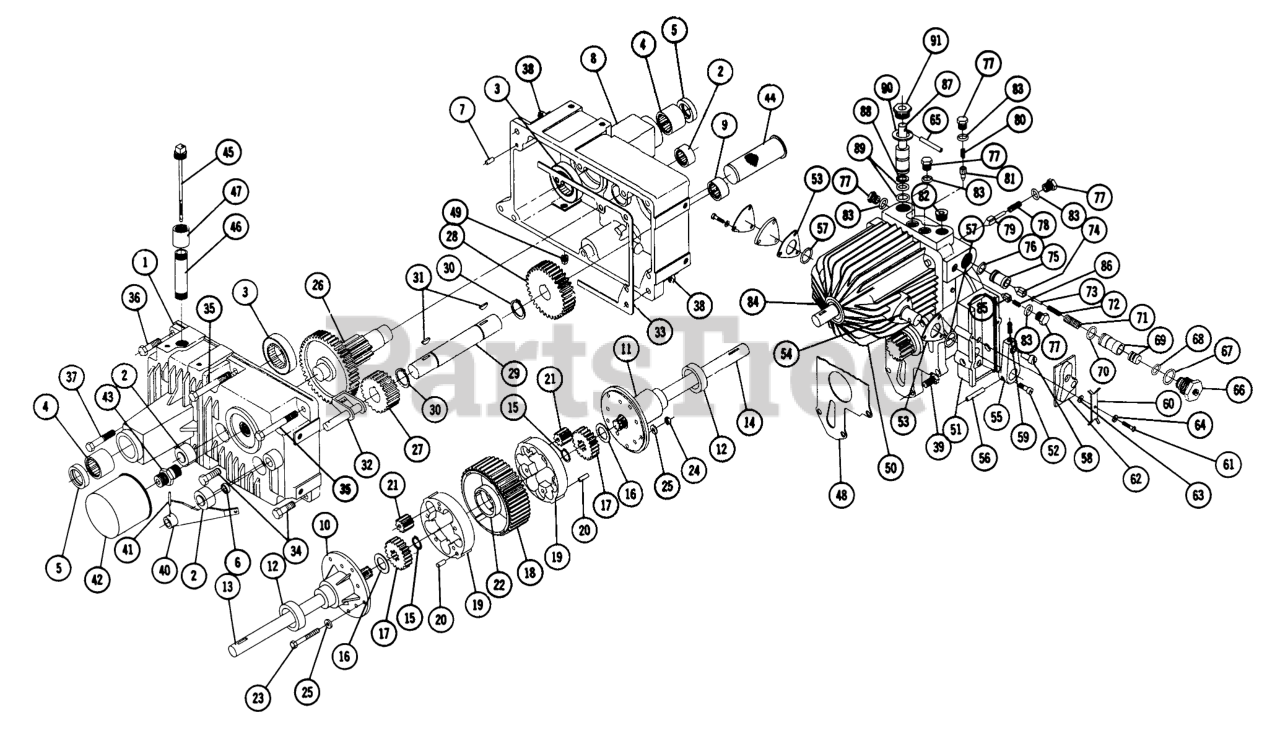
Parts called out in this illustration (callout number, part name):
2	BEARING-NEEDLE
5	SEAL-OIL
7	PIN-DOWEL
17	SIDE GEAR
19	BULLT 252
23	Bolt Hex 3 1/4
24	3/8-16 E.S.
25	Washer
31	Key
36	Bolt 3/8-16 x 2 1/4
37	Bolt Hex 3/8-16 x 1
38	Nut
39	Bolt, 3/8-16 x 1
43	FITTING
46	Nipple 1/2 Pipe x 31/2
47	Coupling 1/2 Pipe
50	SER BULLT 437B
55	Arm-Cam Follower
56	ROLL PIN 1/4 X 1-1/4
57	RING
59	Set Screw-1/4-20 x 1/2
61	Bolt-Rd. Heed #8-32 x 1/2
62	CAM
63	Washer
64	Lockwasher
65	SPIROL PIN
68	O RING
70	O RING
72	SPRING
78	SPRING-SUNDSTRAND
80	Spring Charge Pump Valve
83	O RING
